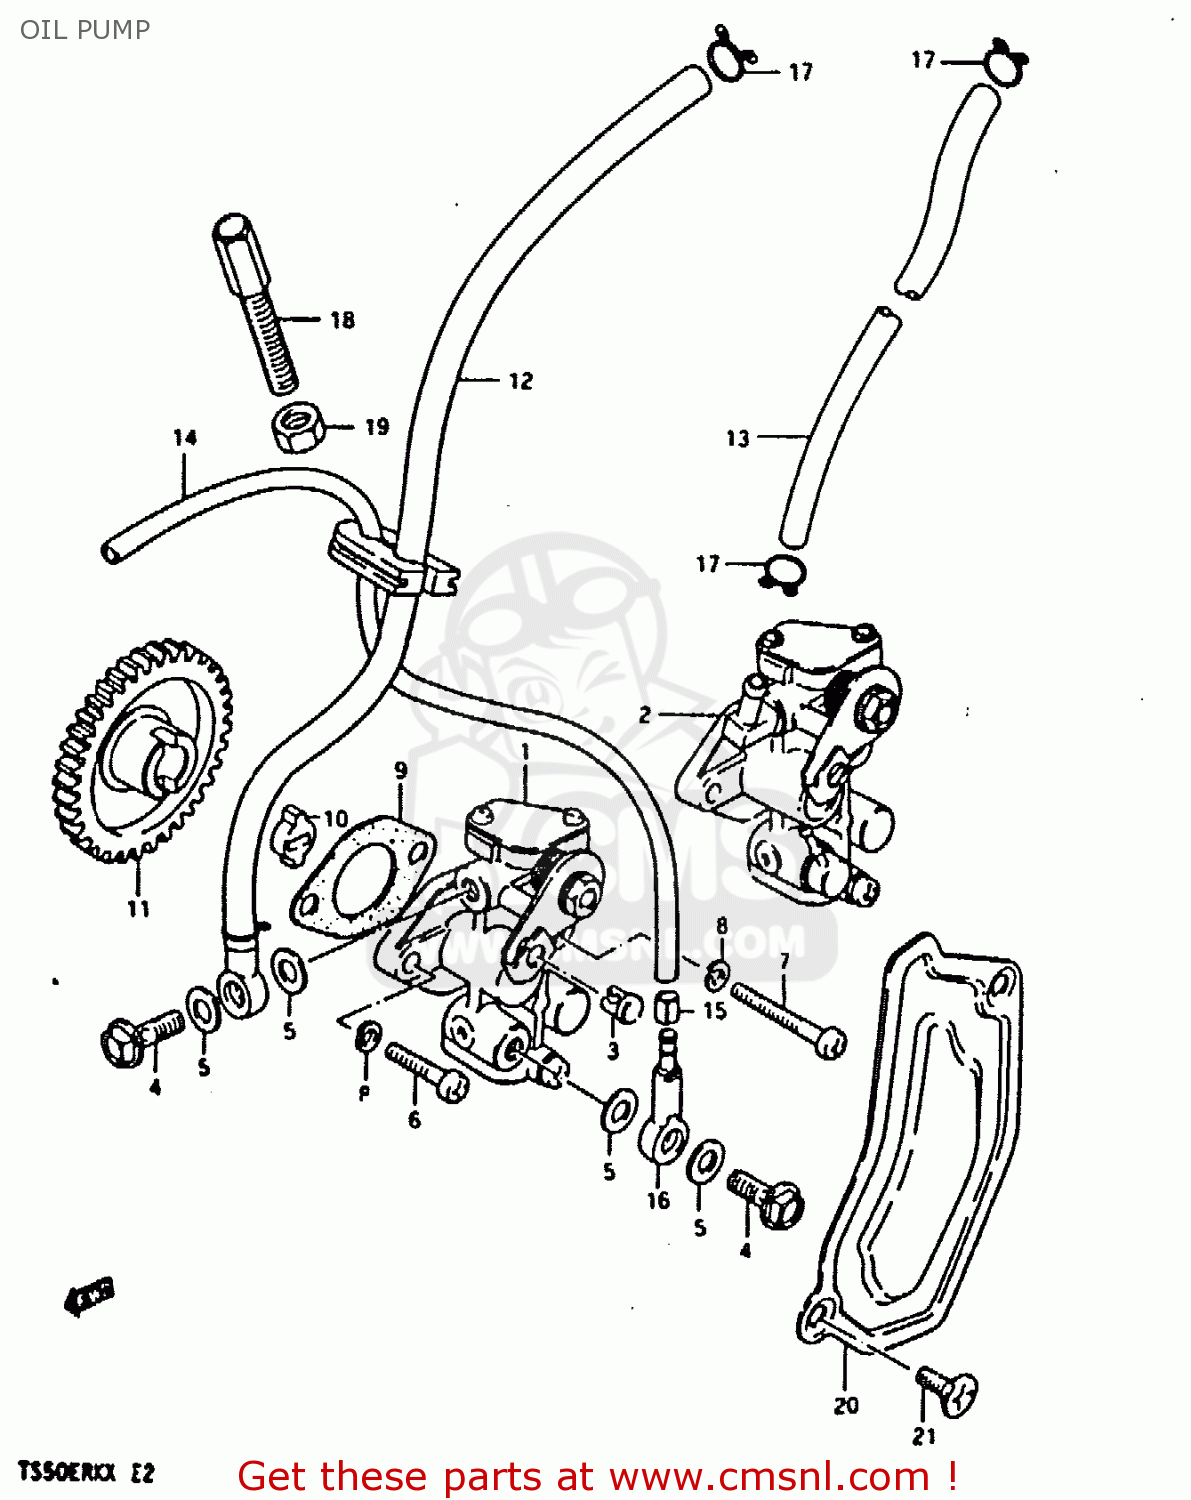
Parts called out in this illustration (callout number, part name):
1	PUMP ASSEMBLY,OIL
2	PUMP ASSY,OIL
3	TERMINAL,CABLE
4	UNION BOLT
5	GASKET(6.2X11X1).2 (NAS)
6	SCREW
7	SCREW
8	LOCK WASHER
9	GASKET,OIL PUMP (NAS)
10	PIECE,OIL PUMP DRIVE
11	GEAR,OIL PUMP DRIVE
12	HOSE, OIL INLET
13	HOSE
14	HOSE,OIL
15	CLIP
16	VALVE,CHECK
17	CLIP
18	BOLT
19	NUT
20	CAP,OIL PUMP INSPECTION
21	SCREW
